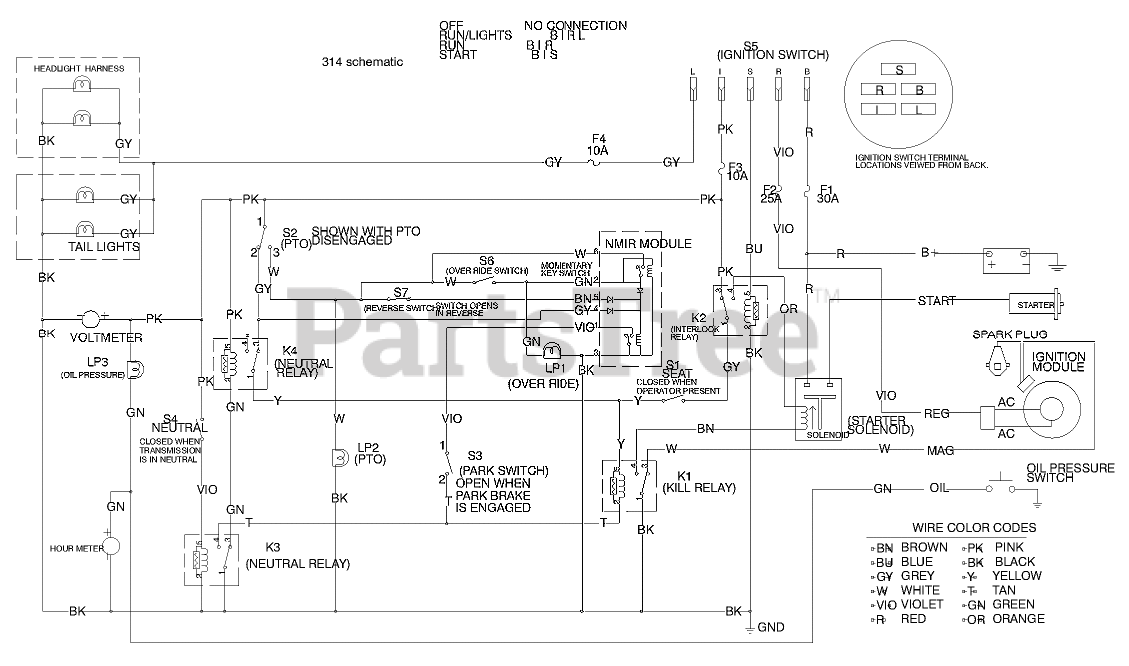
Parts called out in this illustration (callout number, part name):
F1	FUSE-30 AMP
F2	FUSE-BLADE, 25 AMP
F3	FUSE-10 AMP
F4	FUSE-10 AMP
